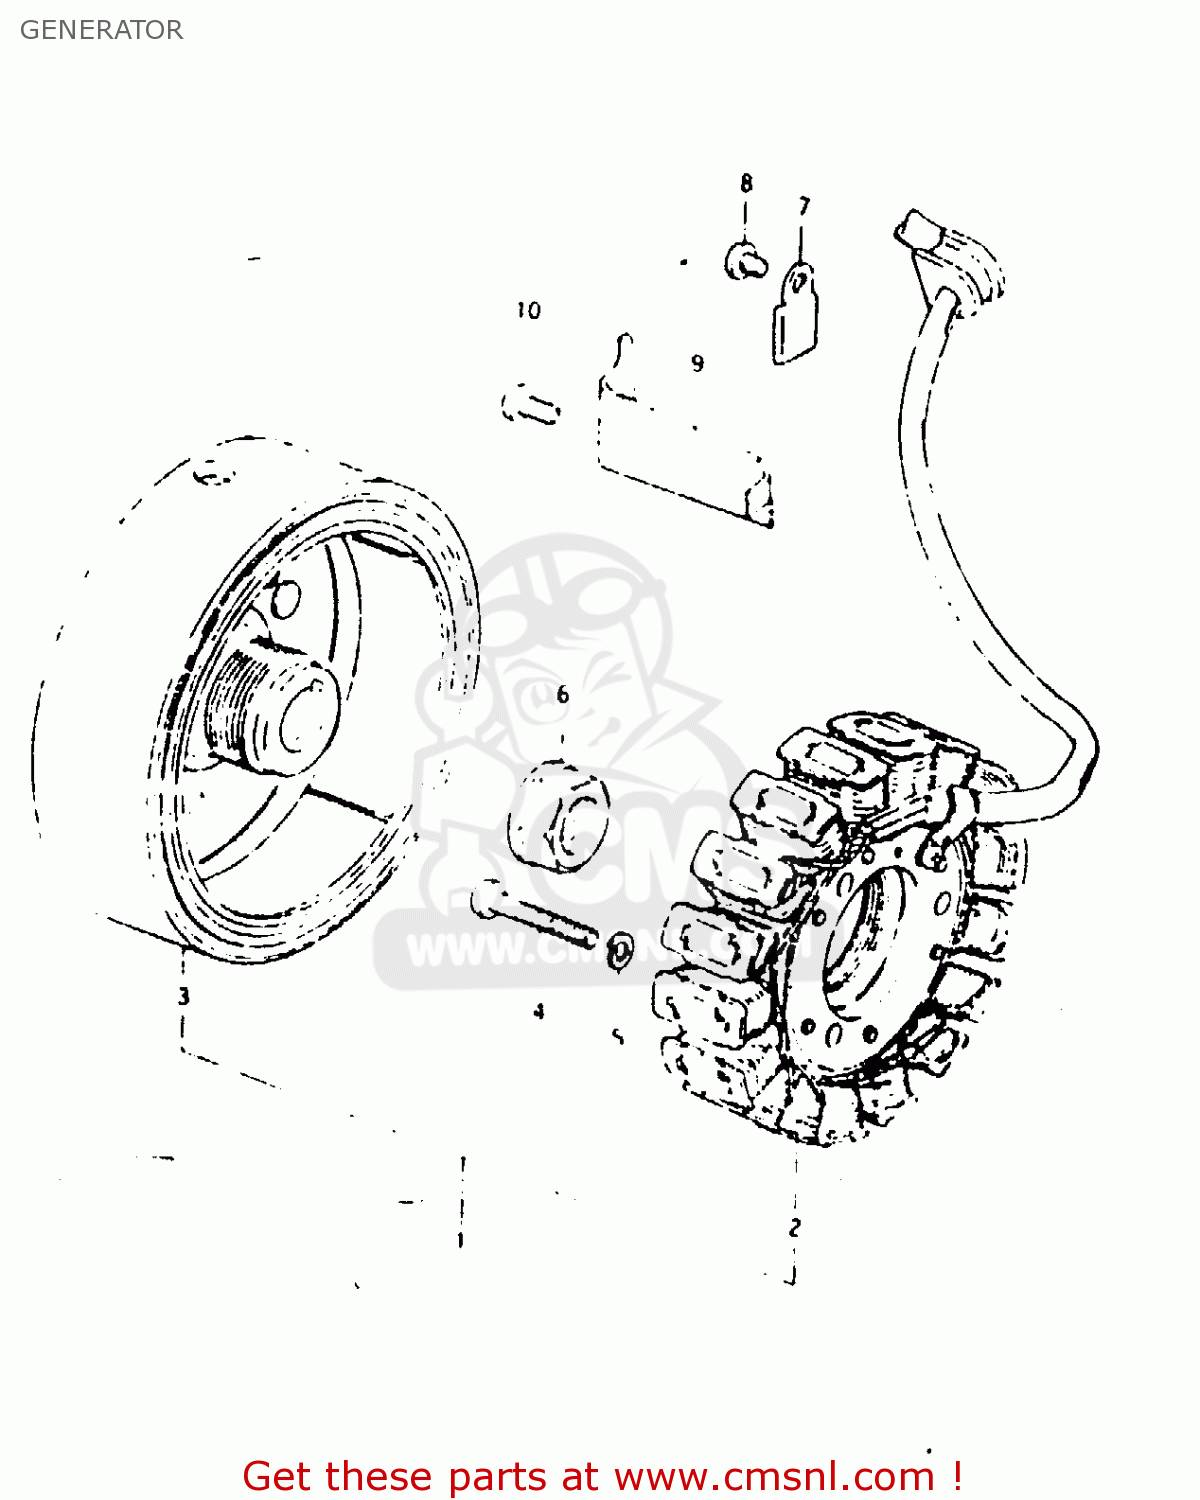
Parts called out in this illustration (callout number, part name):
1	GENERATOR ASSY
2	STATOR
3	ROTOR ASSY
4	SCREW
5	LOCK WASHER
6	NUT,GENERATOR ROTOR
7	CLAMP,GENERATOR LEAD WIRE
8	SCREW
9	CLAMP,GENERATOR LEAD WIRE
10	SCREW
